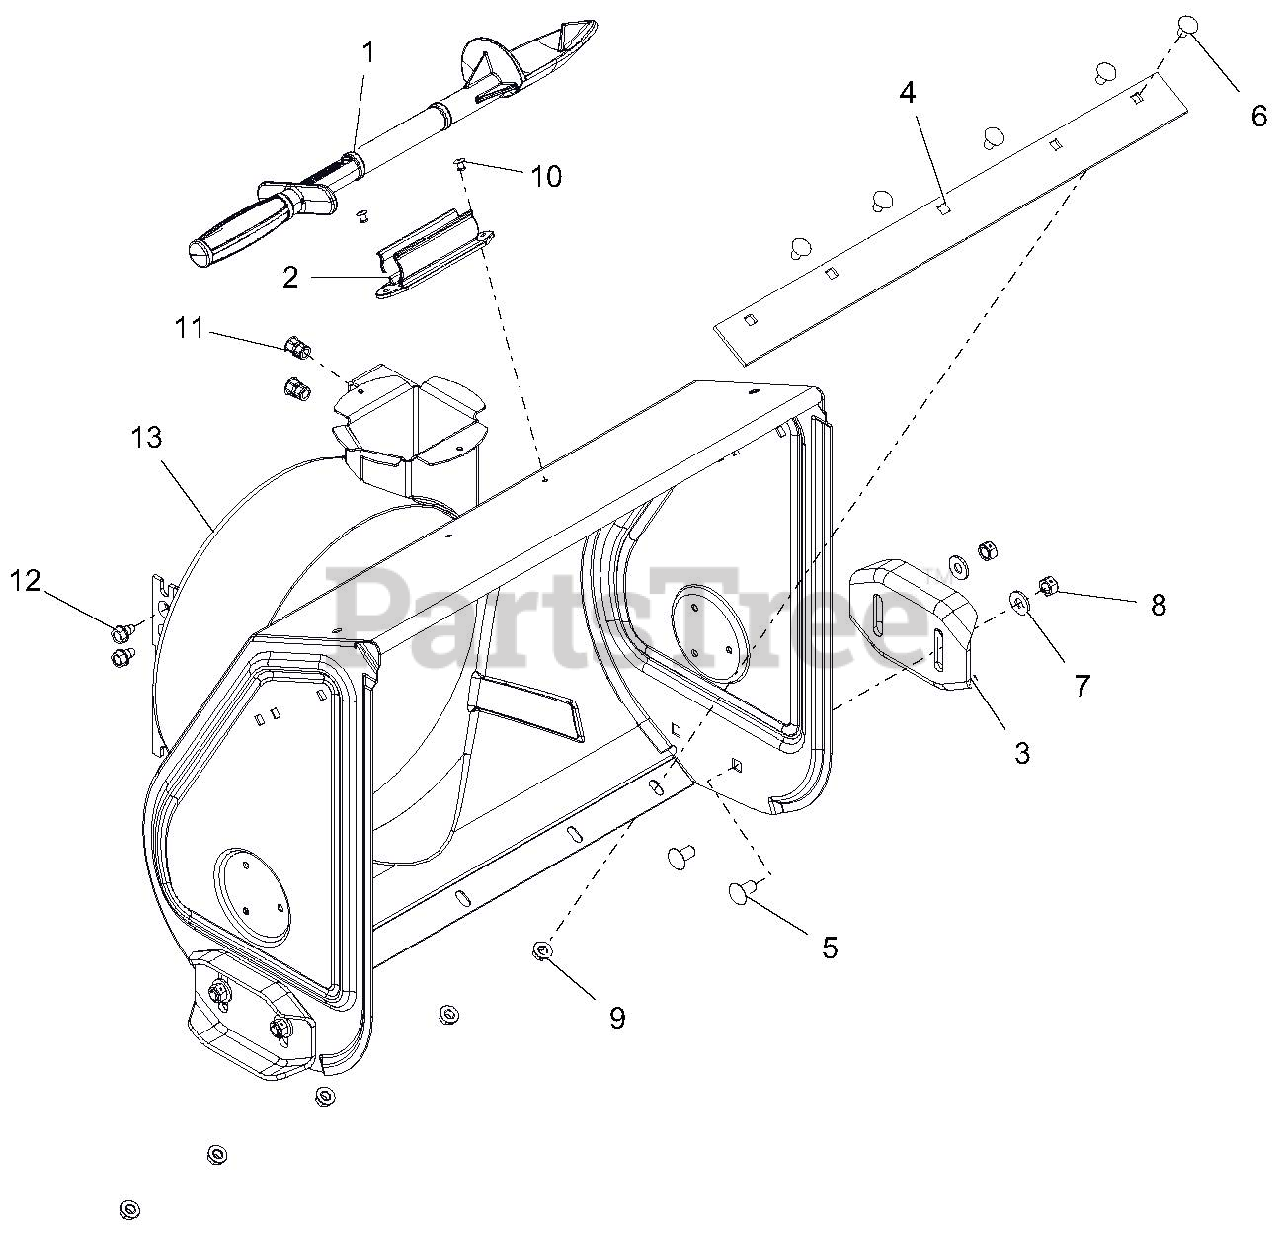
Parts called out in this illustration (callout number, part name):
1	DEVICE, SNOW CLEAN OUT
2	MOUNT, SNOW CLEAN OUT
3	SKID SHOE, REVERSIBLE - ORANGE
4	SCRAPER BLADE, 22" COMPACT
5	@BLT-RHDSSQNK .38-16X.75 G5YZ
6	BLT,RDSHHDSQSHNK .31-18X.62 YZ
7	@WSHR-FL-STL.38X.875X.083 YWZC
8	@NUT-LK-CTR .38-16 YWZC
9	@NUT-LK-TOP-FLG .31-18 YWZC
10	RVT-POP .187 YZ
11	NUT, THREADED INSERT .38-16
12	@SCR-TAP .31-18X.50 HWH TR YWZ
13	BLOWER HOUSING, 22" HI ORANGE
